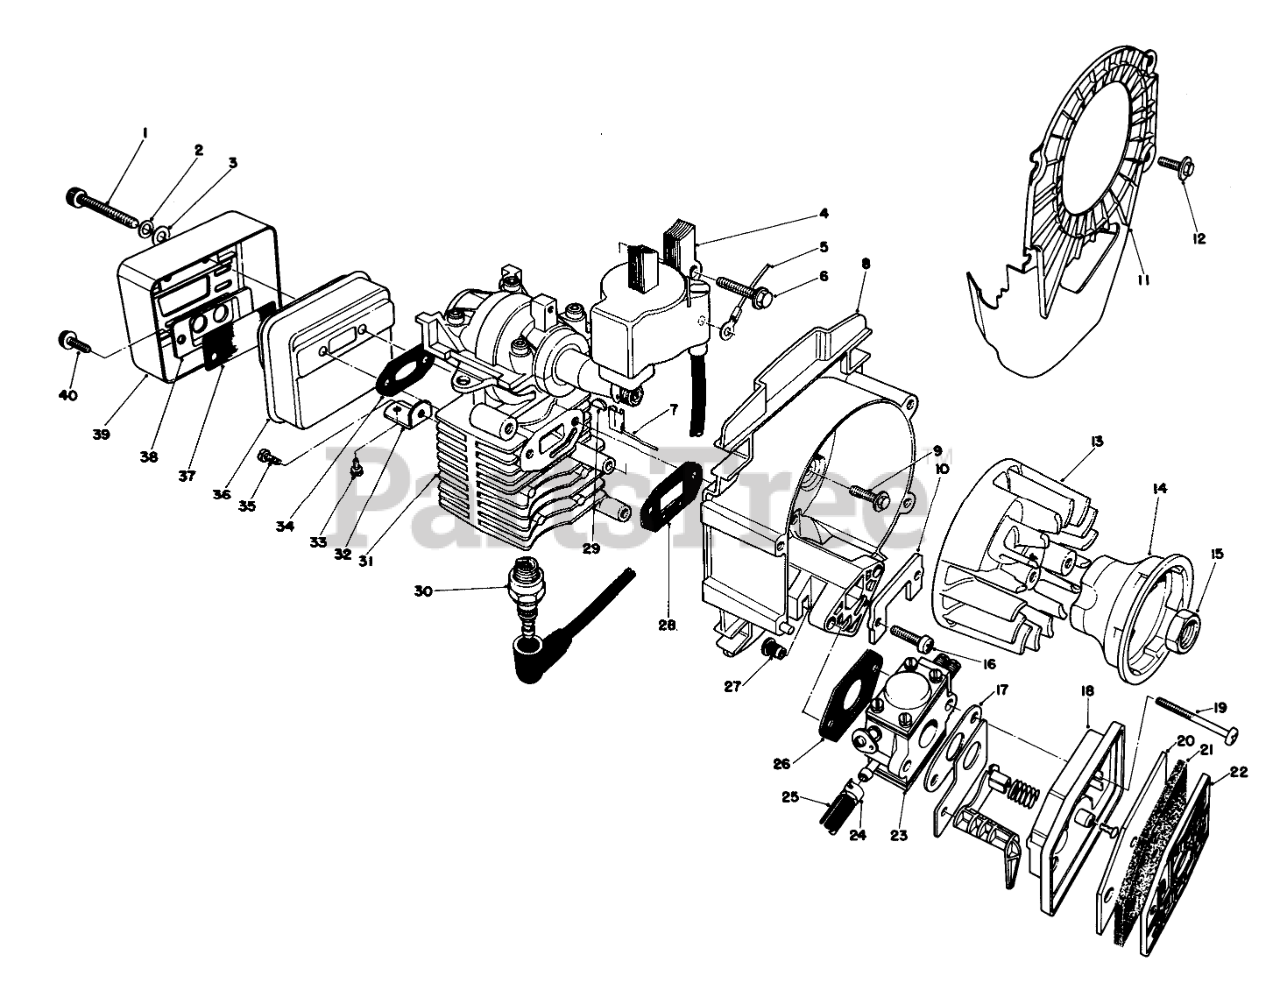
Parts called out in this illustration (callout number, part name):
1	MUFFLER SCREW
2	WASHER-LOCK
3	WASHER-FLAT
4	CDI Module
5	Wire-Ground/Switch
6	Screw CDI
7	Wire-Coil/Switch
8	Backing Plate Assembly (Incl. Ref. #31)
9	Screw
10	Plate-Stress
11	Cooling Shroud
12	Screw-Shroud
13	FIywheel
14	Cup-Starter
15	NUT-JAM
16	Screw, Intake
17	CHOKE GASKET
18	Choke & Spitback Cup Assy.
19	Screw-Carburetor
20	FILTER FELT
21	FILTER FOAM
22	FILTER COVER
23	Carburetor
24	CLAMP-HOSE
25	Hose, Fuel Line
26	Gasket, Carburetor
27	THREADED INSERT
28	Gasket, Intake
29	FLYWHEEL KEY
30	SPARK PLUG (NGK)
31	Short Block
32	Tab Shield
33	Screw-Heat Shield
34	EXHAUST GASKET
35	Screw Shield Tab
36	Muffler Assembly (Incl. Ref. #37, 38 & 40)
37	Spark Arrestor
38	MUFFLER OUTLET PLATE
39	MUFFLER SHIELD
40	Screw-Outlet
